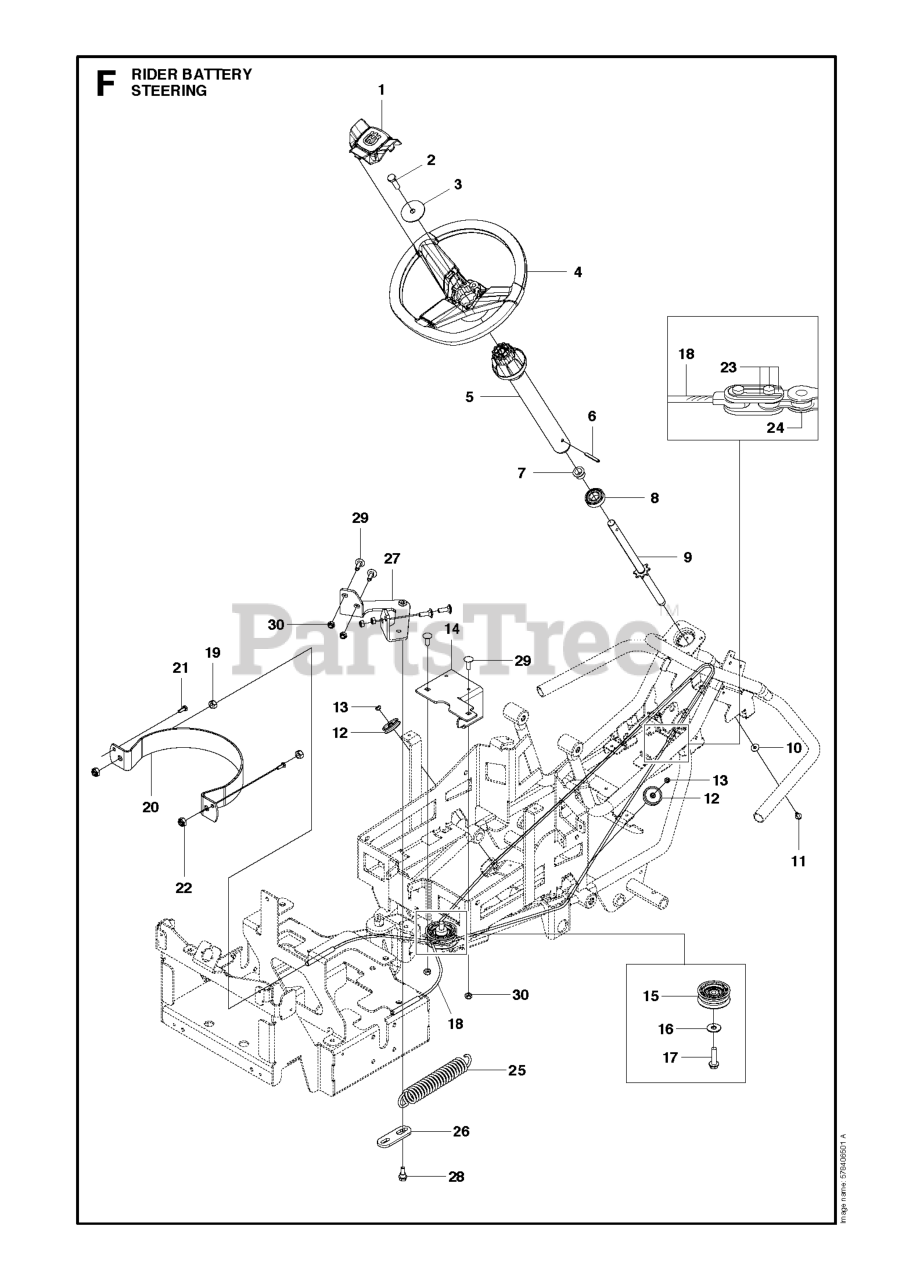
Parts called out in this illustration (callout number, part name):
1	RP INSERT.CAP.WHL.STRG.HUSQ.
4	RP WHEEL.STEER.HUSQ.PREM.OVMLD
8	BALL BEARING 6004-2RS1
9	STEERING ROD
10	WASHER - 26X6.5X1.6
11	SCREW EHHFM
13	LOCKNUT M6
18	WIRE ASSY
19	NUT
20	GUIDE RAIL
21	SCREW
22	NUT
24	STEERING CHAIN
30	LOCKNUT M8
